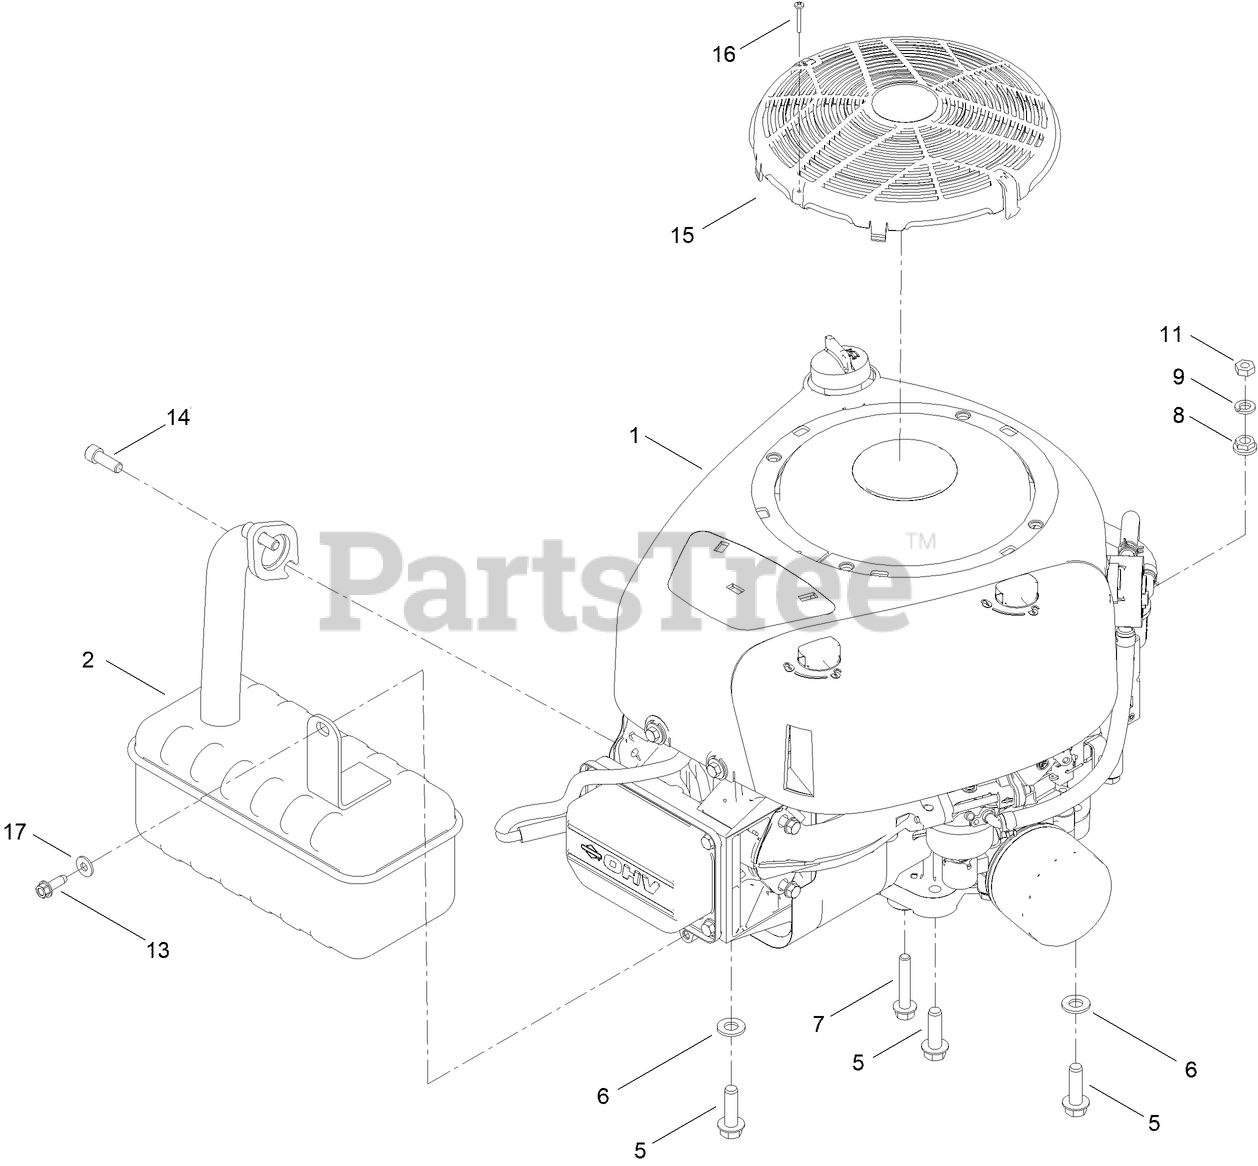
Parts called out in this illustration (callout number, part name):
1	ENGINE-BRIGGS, 1550 SERIES
2	MUFFLER
5	SCREW-HWH, THD ROLL
6	WASHER-FLAT
7	SCREW-HWH
8	NUT-HF
9	WASHER-LOCK
11	NUT-JAM
13	SCREW-HWHTF
14	SCREW-HSH
15	COVER-FAN
16	SCREW-FAN
17	WASHER
